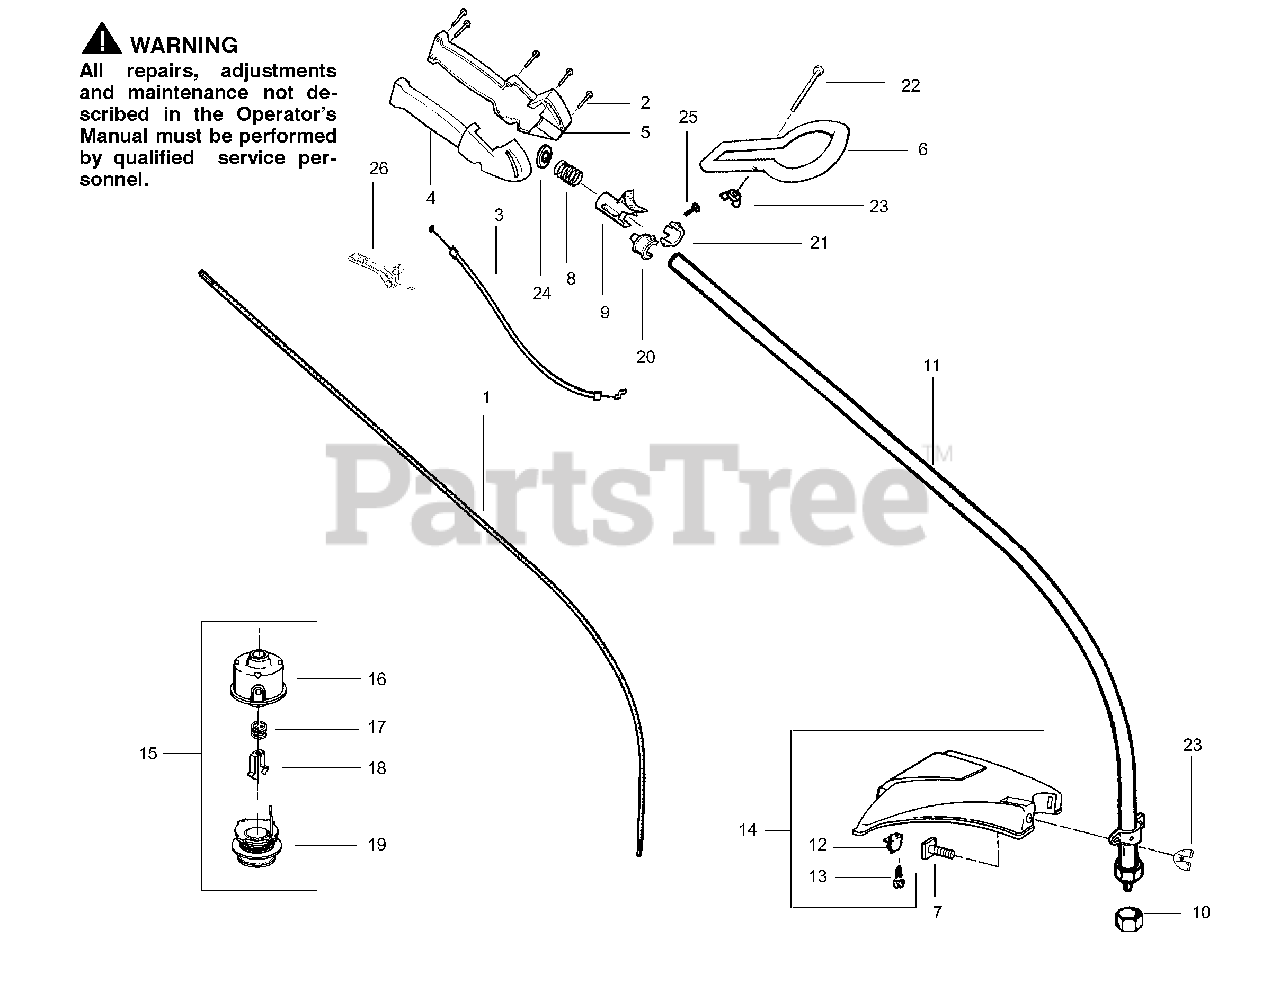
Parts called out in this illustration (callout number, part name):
1	Drive Shaft
3	Throttle Cable Ass'y.
4	Throttle Hsg. (Right)
5	Throttle Hsg. (Left)
6	Assist Handle
7	Bolt-Shield
8	Spring-Compression
9	Actuator
10	Dust Cup
11	Drive Shaft Hsg. Ass'y
12	Line Limiter
13	Screw-Line Limiter
14	Shield Kit Ass'y.
15	Cutting Head Ass'y.
16	Hub Ass'y
17	Spring-Return
18	Retainer-Spool
19	Spool w/Line
20	Locator-right
21	Locator-left
22	Bolt-Handle
23	Wingnut
25	Screw
